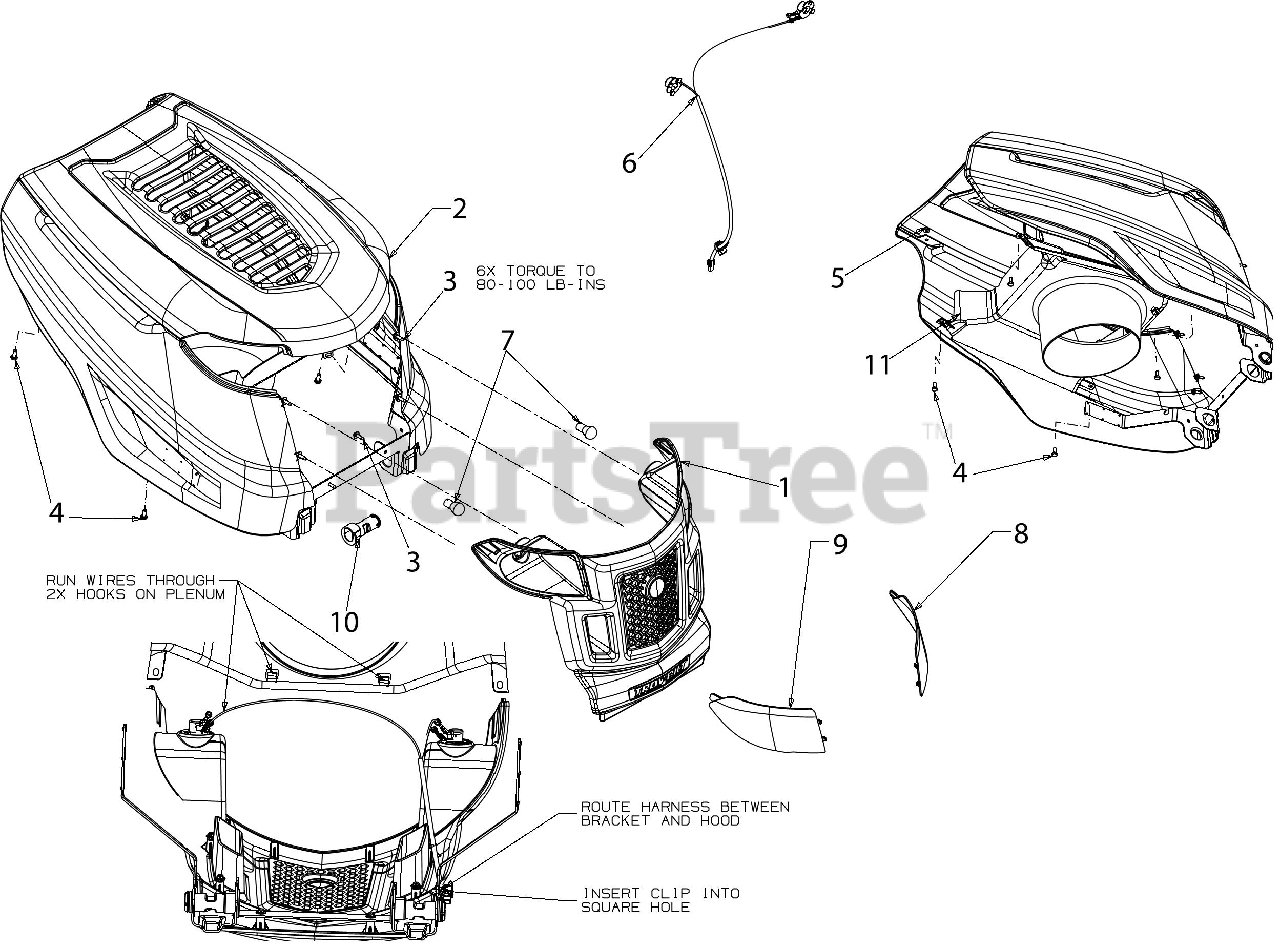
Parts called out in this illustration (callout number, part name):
1	GRILLE ASSEMBLY (TROY-BILT)
2	HOOD ASSEMBLY(K STYLE)
3	SCREW 1/4-10 x .750
4	SCREW 1/4-20 x .620 GR5
5	FLANGE LOCK NUT
6	HEADLIGHT HARNESS
7	MINIATUURE BULB 12V
10	HOOD PIVOT PIN
11	PLENUM (K-STYLE)
